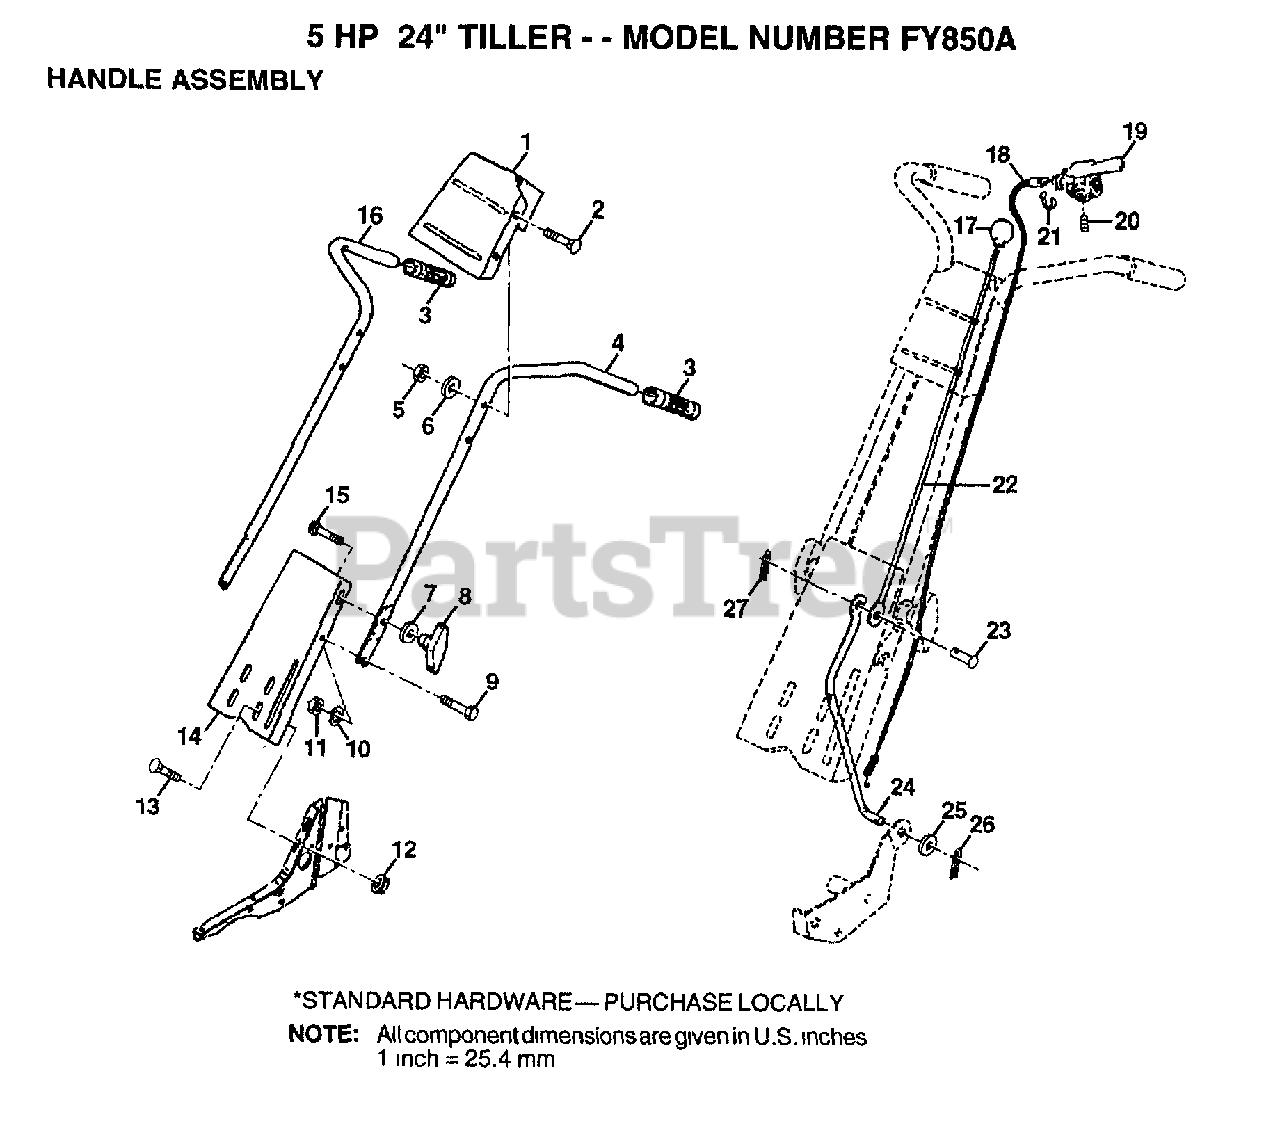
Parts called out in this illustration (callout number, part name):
1	HANDLE BRKT
2	BOLT
6	WASHER
7	WASHER
10	LOCKWASHER
11	NUT.HEX.5/16-18
12	NUT
13	BOLT
15	BOLT
17	KNOB T(3/8 HOLE)
18	CABLE CLUTCH T
19	CONTROL LEVER TI
20	SCREW
21	E-RING
22	ROD REVERSE TI
23	RIVET.RD.HD.DRILL
24	REVERSE ROD TI
25	WASHER
26	COTTER PIN
